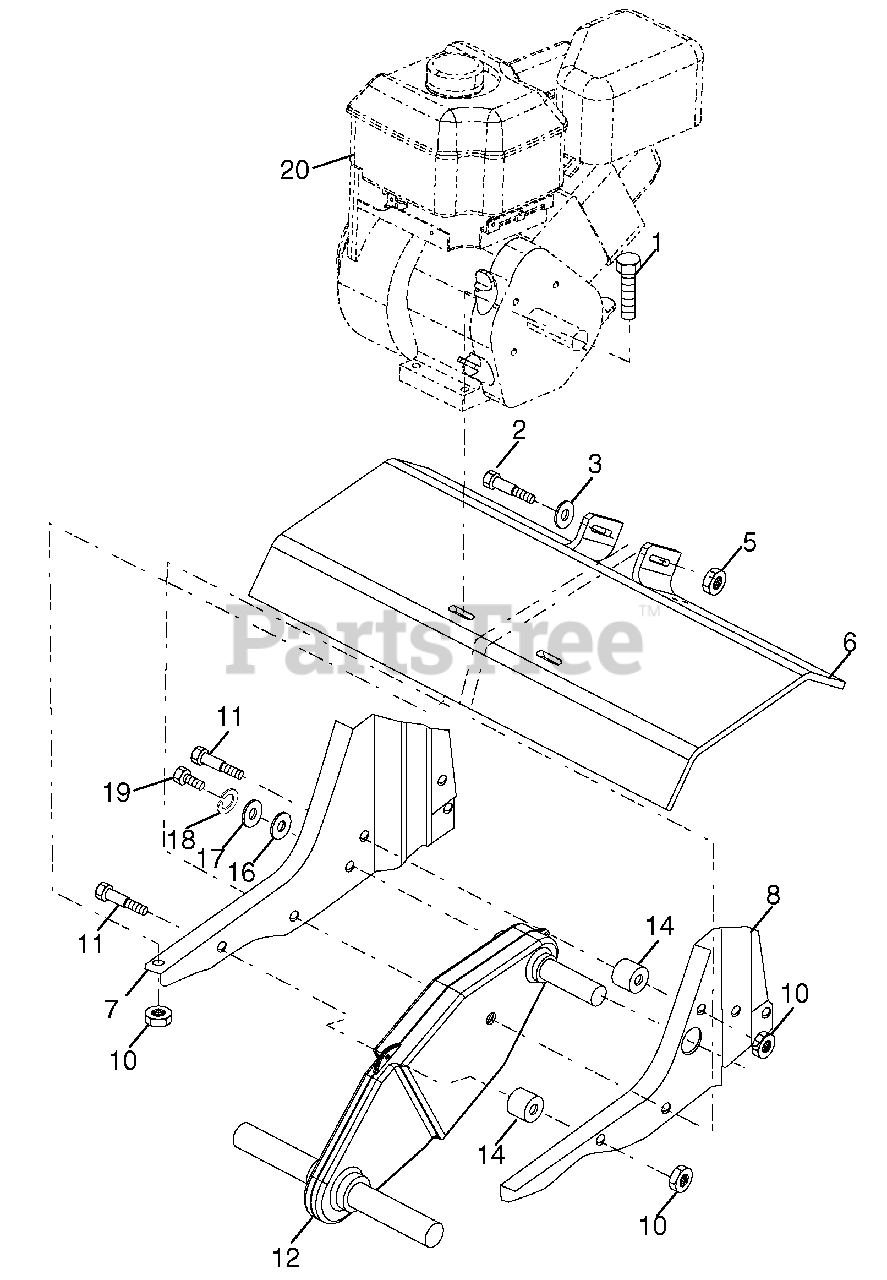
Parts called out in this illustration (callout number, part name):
1	Bolt, Hex Head, Grade 2 5/16-18 x 1-1/2
2	Bolt, Hex Head 3/8-16 x 3-1/4
3	Washer 13/32 x 13/16 x 11
5	Nut, Hex, Flangelock 3/8-16
6	Shield, Tine
7	Bracket, Engine, R.H.
8	Bracket, Engine, L.H.
10	Nut, Hex, Flangelock
11	Bolt, Shoulder
12	Transmission
14	Spacer, Split
16	Washer 9/32 x 7/8 x 12 Gauge
17	Washer 9/32 x 1-1/4 x 16 Gauge
18	Washer, Lock 1/4
19	Bolt, Hex Head, Grade 5 1/4-28 x 3/4
